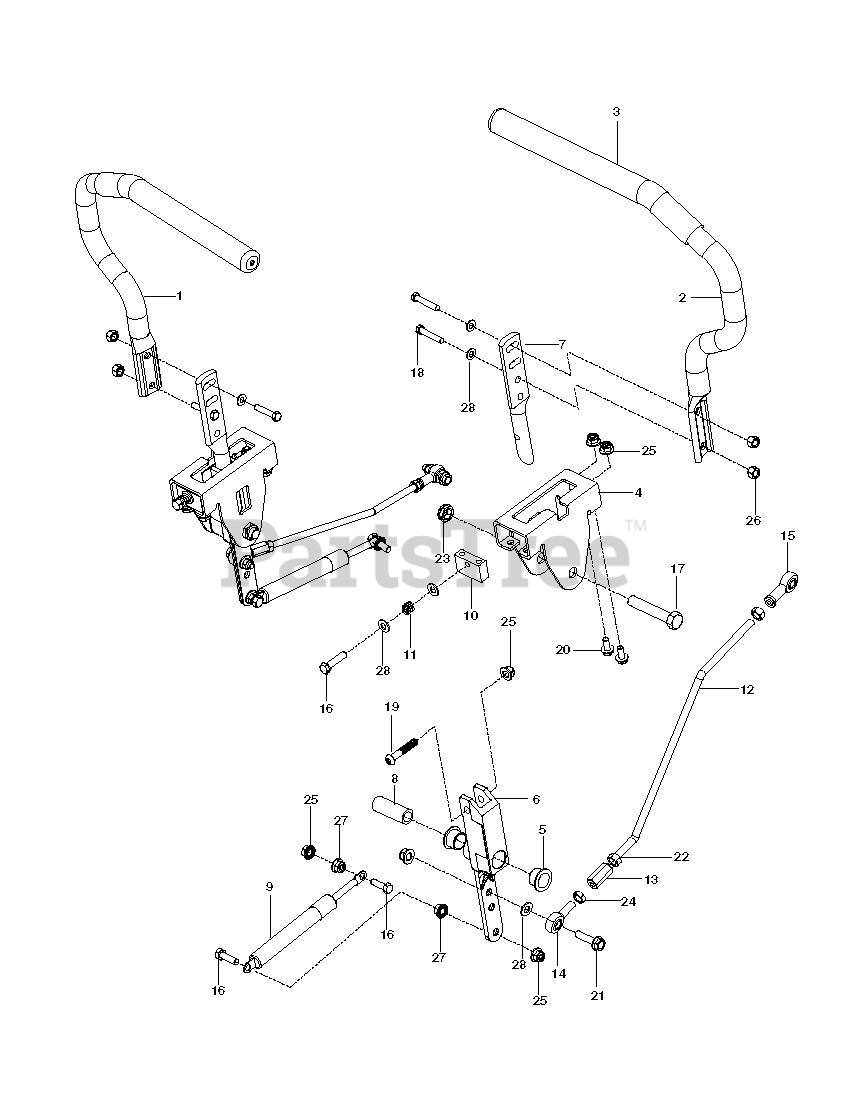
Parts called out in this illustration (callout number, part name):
1	LEVER DRIVE W/GRIP RT
2	LEVER, DRIVE W/GRIP LT
3	GRIP - DRIVE LEVER
4	BRACKET, CONTROL
5	BEARING, FLANGE
6	LEVER CONTROL PIVOT
8	SPACER, PIVOT CONTROL
9	DAMPENER
10	BLOCK, TRACKING
12	ROD, CONTROL
13	ROD END COUPLER
14	RH ROD END
15	ROD END LH
16	HCS 5/16C X 1 1/4
17	HCS 1/2C X 2 3/4
18	CAPSCREW 5/16 X 1/1/2 HEX HEAD
20	HHFS 5/16-18 X 3/4
21	HHFS 5/16-18 X 1.25 TPBLT GD 5
22	NUT 5/16F
23	NUT 1/2-13 HEX JM NYL
24	NUT 5/16F LEFTHAND
25	5/16-18 NYLOC FLANGE NUT
26	NUT 5/16 NYLOC
27	NUT 5/16C WHIZ
28	FLAT WASHER 5/16 SAE
